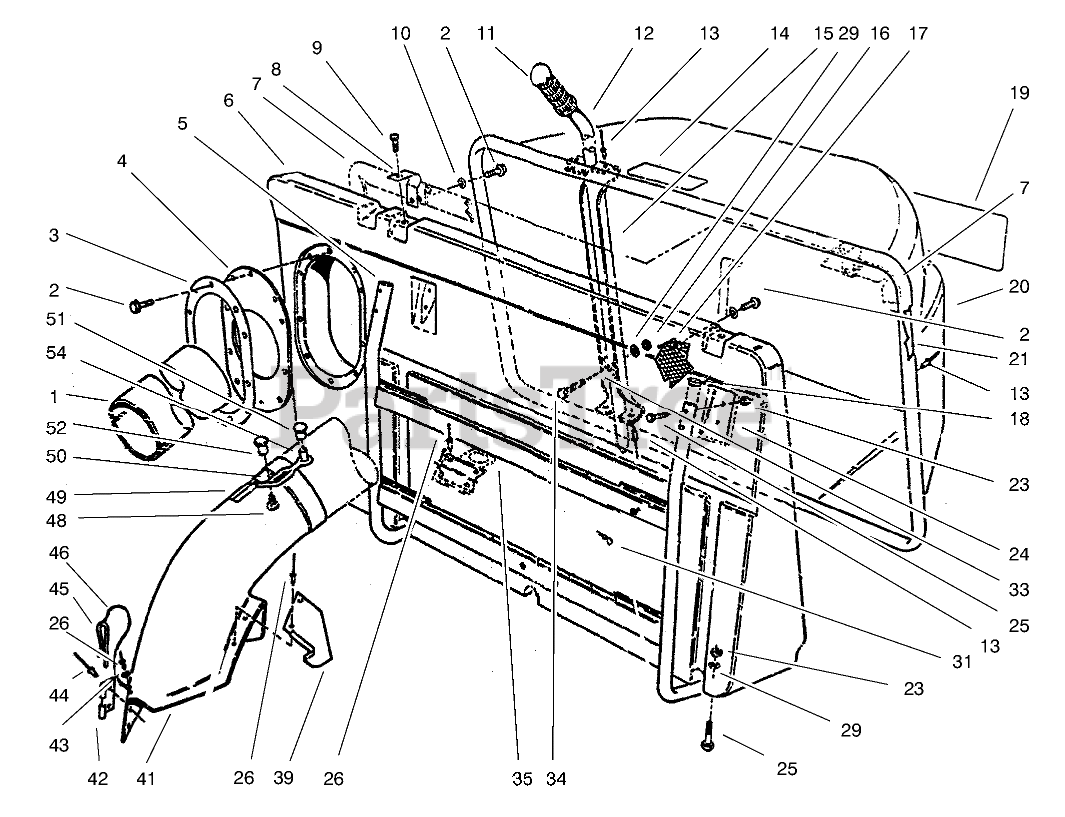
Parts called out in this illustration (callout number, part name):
1	GRASS DISCHARGE TUBE
2	SCREW-HWHTF
3	RING-RETAINING
4	RING-RETAINER, RUBBER
5	Frame
6	BAG-FRONT
7	SEAL-BAG
8	Bracket-Hinge
9	SCREW-HH
10	WASHER-FLAT
11	GRIP-HANDLE
12	HANDLE-DUMP
13	RIVET-POP
14	DECAL - WARNING
15	Channel-Dump Handle
16	NUT-LOCK, NI
17	Screen Bag
19	DECAL-BAG, EASY EMPTY
20	BASKET-GRASS
21	Frame-Grass Basket
23	NUT-LOCK, NI
24	Plate-Backup
25	SCREW-HH
26	RIVET-BLIND
29	WASHER-FLAT
31	PIN-HAIR
33	GUIDE-HANDLE, DUMP
34	SCREW-HH
35	Latch
39	CHUTE SUPT BRKT
41	Chute Ass-y. (Incl. Ref. #26, 39, 42-46, 48, 49, & 52)
42	BRACKET-MOUNTING, CHUTE
43	WASHER-PLAIN
44	RIVET-BLIND
45	PIN-LOCKING, CHUTE
46	LANYARD
48	SCREW-HWH
49	DECAL-DANGER
50	RETAINER-DUCT
51	SPACER-INTERLOCK
54	FASTENER-PANEL
